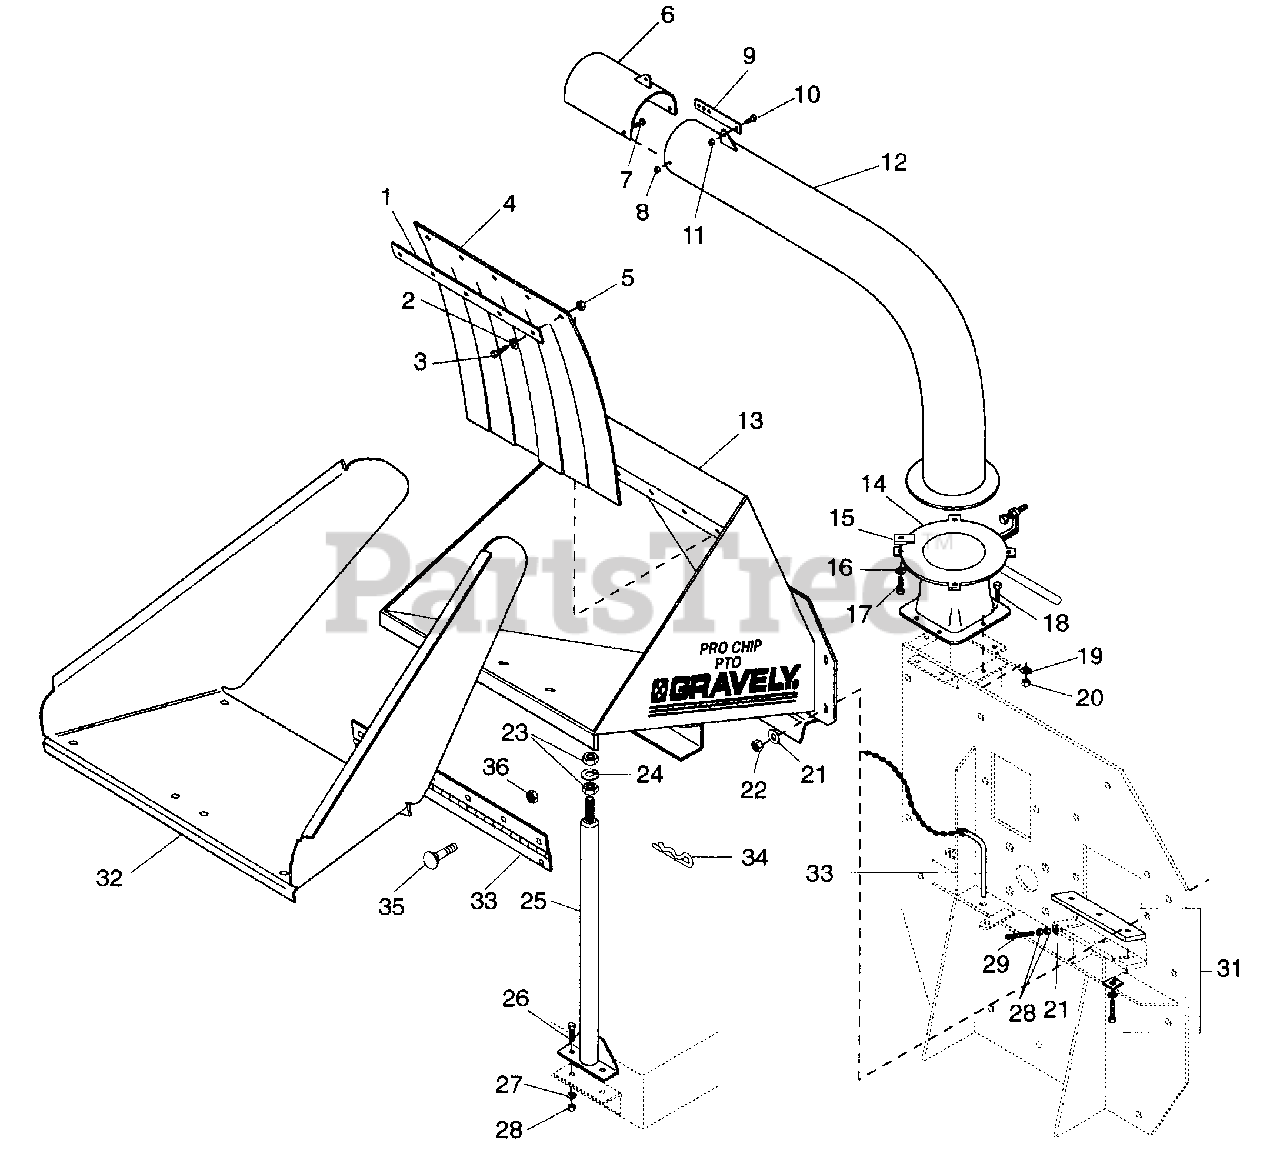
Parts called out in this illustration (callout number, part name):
2	Washer-Flat-Steel .265 x .500 x .087
3	Bolt-Hex .25-20 x .75 Grade 5
4	Rubber Flap
5	Nut-Locking Top .250-20
6	Deflector
7	Bolt-Hex .38-16 x 1.0
8	Nut-Locking Top .375-16
9	Deflector Arm
10	Bolt-Hex .31-18 x 1.00 Grade 5
11	Nut-Locking Top .312-18
12	Discharge Chute
13	PTO-Hopper Weldment
14	Discharge Neck
15	Clamp
16	Washer-Lock .312 x .097
17	Bolt-Hex .31-18 x .88 Grade 5
18	Bolt-Hex .25-20 x 1.00 Grade 5
19	Washer-Lock .250 x .077
20	Nut .250-20
21	Washer-Flat-Steel .406 x 1.000 x .188
22	Nut-Locking Top .375-16
23	Nut-Jam .75-10
24	Washer-Lock .750 x .188
25	Hopper Stand
26	Bolt-Hex .38-16 x 1.00 Grade 5
27	Washer-Lock .375 x .155
28	Nut-Hex .375-16 Grade 2
29	Screw-Set .38-16 x 3.50
30	Flywheel Lock Pin
31	Bed Knife Kit 210/PTO
32	Safety Bonnet Weldment
33	Hinge
34	Pin-Hair Internal .14 x .43 x 2.75
35	Bolt Round Head Square Neck .25-20 x .50
36	Nut-Locking-Center .250-20
